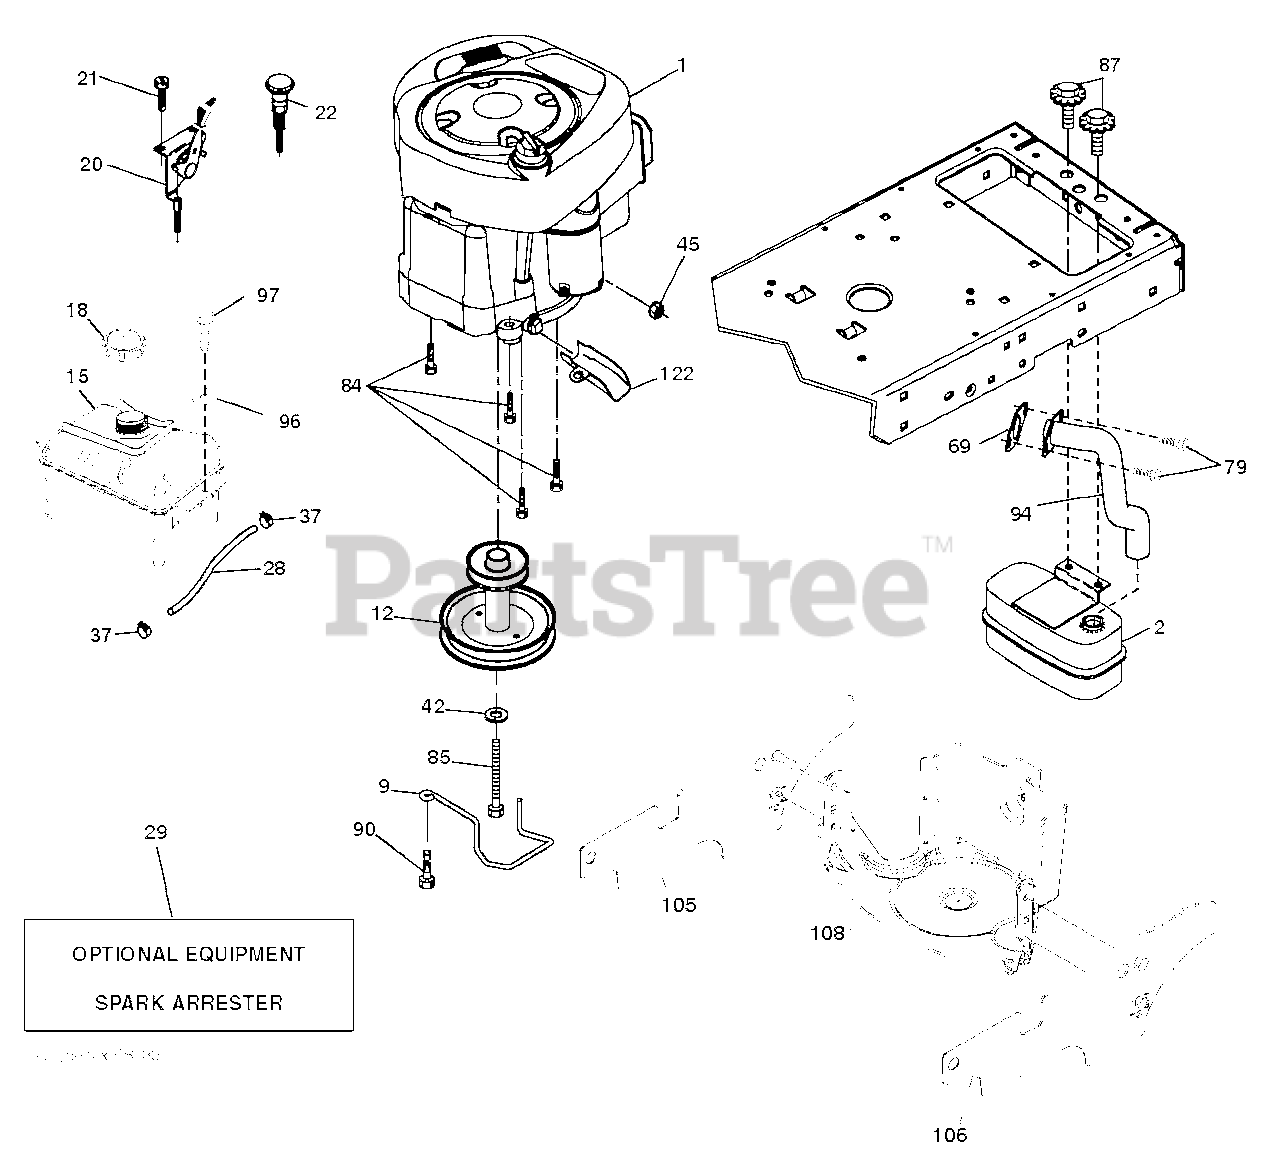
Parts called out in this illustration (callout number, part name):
2	MUFFLER.SINGLE.CYL.KOHL/B&S
9	KEEPER.BELT.ENGINE.3.25
12	PULLEY ENGINE
15	TANK FUEL FRT 1.5 GAL
18	CAP ASM.FUEL.2.25"FR.
20	CONTROL.TH/CK.C.
21	SCREW.#10 X 0.750.BOS THREAD
28	LINE.FUEL.20
29	ARRESTER SPARK (OPTIONAL)
37	HOSE CLAMP
42	LOCKWASHER
45	NUT
69	REPL BY 532 27 22-93
79	SCREW.SOCKET HD.5/16-1
84	SCREW.3/8-16
85	BOLT HEX 7/16-20X4-1/4"
87	BOLT, 5/16-18 X 1 3/4
90	SCREW 3/8-16X1
94	EXHAUST.TUBE.B&S.
97	SCREW HEXWSHR 1/4-20X3/4
122	EXTENSION DRAIN OIL
